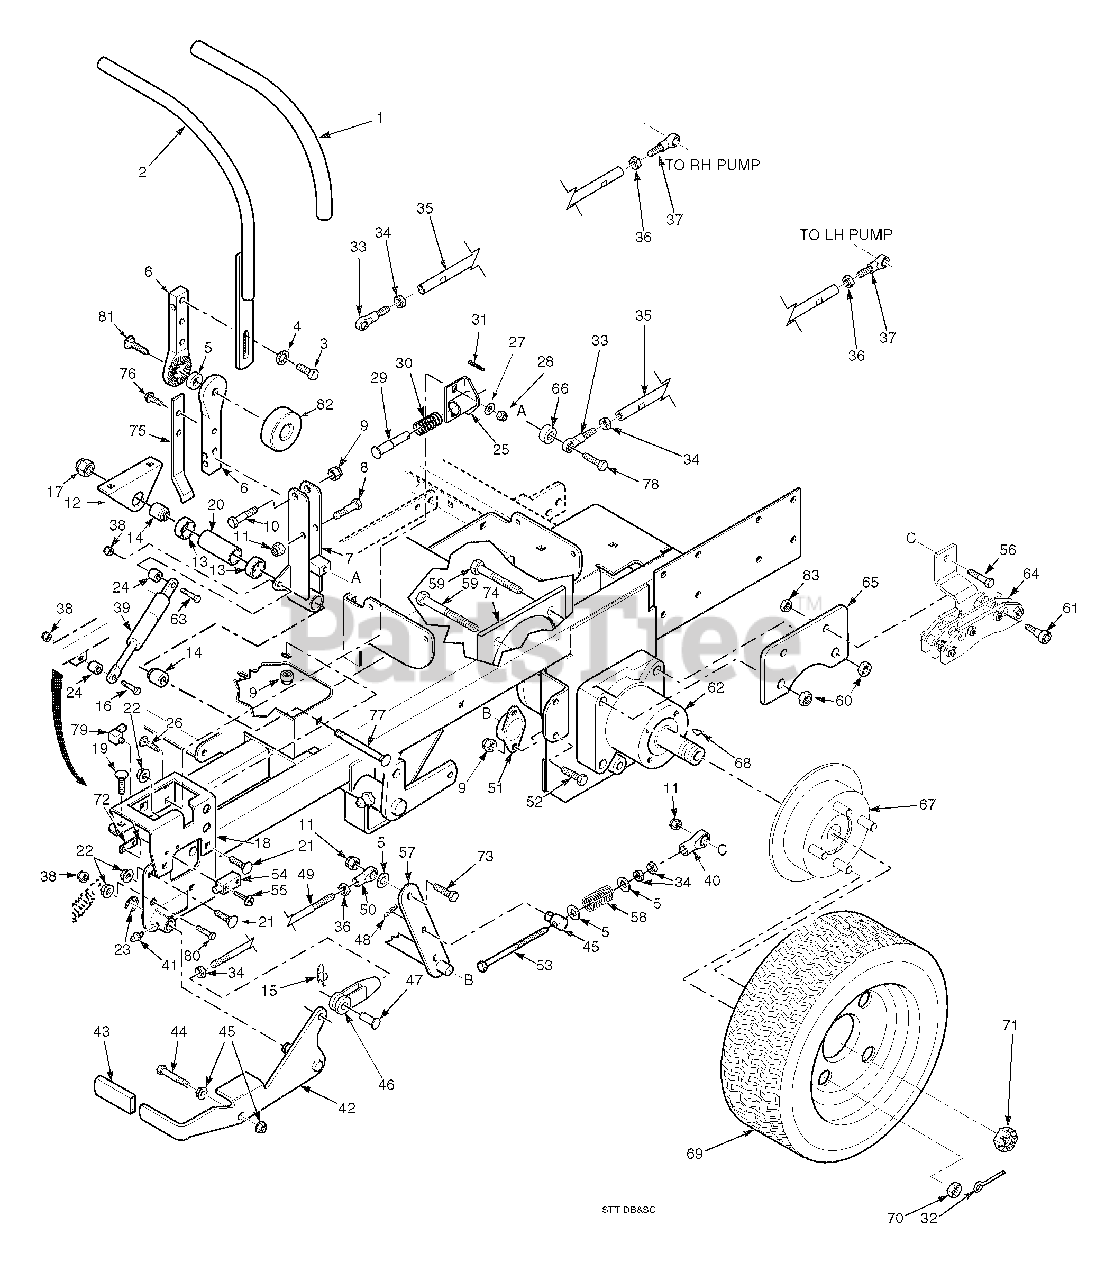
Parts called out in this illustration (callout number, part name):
1	Grip, Handle Bar
2	Handle Bar, LH
3	Bolt, Hex Head 5/16-18 x 1"
4	Lockwasher, 5/16"
5	Rubber Spacer
6	Bar, Control Lever
7	Control Lever Weldment, LH
8	Bolt, Hex Head 5/16-18 x 2"
9	Nut, Hex Elastic Stop 5/16-18
10	Bolt, Hex Head 3/8-16 x 2"
11	Nut, Hex Elastic Stop
12	Mount, Control Linkage
13	Ball Bearings, Neutral Return
14	Spacer
15	Pin, Rue Cotter 3/8 Dia.
16	Bolt, Hex Head, 5/16-18 x 2.75 Zinc
17	Nut, Hex Elastic Stop 5/8-11
18	Bracket, Control Lever LH
19	Bolt, Carriage 5/16-18 x 1"
20	Spacer, Bearing
21	Bolt, Carriage 5/16-18 x 3/4"
22	Nut, Hex Serrated Flange 5/16-18
23	Ring, Retaining 5/8" External "E"
24	Spacer
25	Bracket, Neutral Return
26	Bolt, Carriage 1/4-20 x 3/4"
27	Flatwasher, 1/4"
28	Nut, Hex Elastic Stop 1/4-20
29	Pin, Retaining Spring
30	Spring
31	Roll Pin, Spring 5/32 x 3/4"
32	Pin, Cotter 9/16 x 1-1/2"
33	Rod End, Male 3/8-24 RH Thread
34	Nut, 3/8-24 RH Thread
35	Tube, Control Link Air-Cooled Engine
36	Nut, Hex 3/8-24 LH Thread
37	Rod End, Male 3/8-24 LH Thread
38	Locknut, 5/16-18, Elastic Stop
39	Gas Damper
40	Rod End, 3/8-24 RH Female
41	Grease Fitting
42	Lever, Parking Brake
43	Grip, Parking Brake
44	Bolt, Hex Head 3/8-16 x 2-3/4"
45	Swivel Joint
46	Clevis, Traction Control
47	Pin, Clevis 3/8-16 x 1-1/16"
48	Hair Pin Cotter
49	Rod, Parking Brake
50	Rod End, LH Thread
51	Bushing, Self Align
52	Bolt, Hex Head 5/16-18 x 3/4"
53	Bolt, Hex Hd 3/8-24 x 5-1/2"
54	Switch
55	Screw, Hex SLTD WSHR Head #10 32 x 3/4"
56	Brake Linkage, LH
57	Bellcrank, Brake Actuator
58	Spring
59	Bolt, Hex Head 1/2-13 x 2-3/4"
60	Locknut, Hex 1/2-13 Center Lock
61	Bolt, Shoulder 3/8-16 x 2-1/2"
62	Wheel Motor, Hydro-Gear 18E
63	Bolt, Hex Head, 5/16-18 x 1.75, Zinc
64	Brake Caliper
65	Mounting Bracket, Brake
66	Spacer
67	Wheel Hub/Disk Brake Assembly
68	Key, Woodruff 5/16 x 1"
69	Wheel Assembly 24 x 12-12 Turf Master
70	Lug Nut, 1/2-20
71	Nut, Hex Castle
72	Threaded Plate
73	Bolt, Hex Head 3/8-16 x 1-1/2"
74	Plate Weldment, Motor Backing
75	Actuator Switch
76	Bolt, Hex Serrated Flange 5/16-18 x 3/4"
77	Bolt, Carriage 3/8-16 x 4-3/4"
78	Bolt, Hex Head 3/8-16 x 1"
79	Switch
80	Bolt, Hex Head 3/8-16 x 1-1/4" Grade 8
81	Bolt, Carriage 5/16-18 x 1-1/2"
83	Nut, Center Lock 3/8-16
